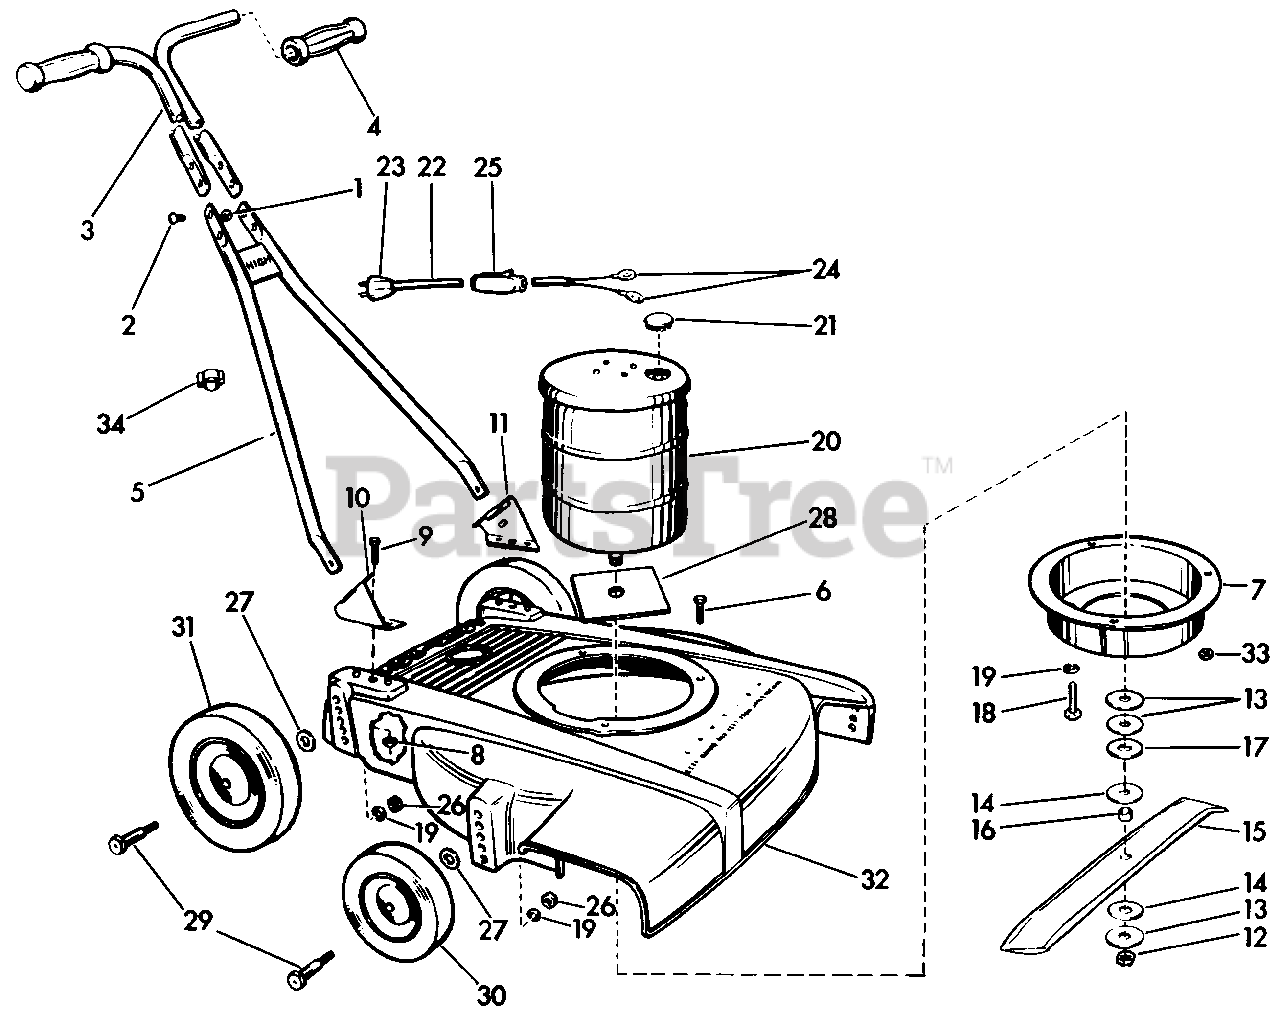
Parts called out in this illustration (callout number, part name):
1	Nut-Handle
2	Screw-Handle and Chute Guard
3	Handle Assembly-Top Half
4	Grip-Handle
5	Handle Assembly-Bottom Half
6	Screw-Plate Adapter
7	Adapter Plate
8	Nut-Handle Bracket
9	Screw-Handle Bracket
10	Handle Bracket-Right
11	Handle Bracket-Left
12	Nut-Blade
13	Washer, Blade
14	Washer-Fiber, Blade
15	Blade-18"
16	Bushing-Blade
17	Washer-Rubber, Blade
18	Screw, Motor Mounting
19	Washer Wheel
20	Motor, 1/3 HP Elec. 3450 RPM
22	Cord Assembly-Electric
23	Plug-Electric
24	Lug-Electric
25	Switch-Toggle
26	Nut-Wheel
27	Washer-Plain Wheel
29	Bolt-Shoulder Wheel
30	Wheel Assembly-6 x 1.50
31	Wheel Assembly-8 x 1.75
32	Housing-18"
33	Nut-Plate Adapter
34	Clip-Electric Cord
